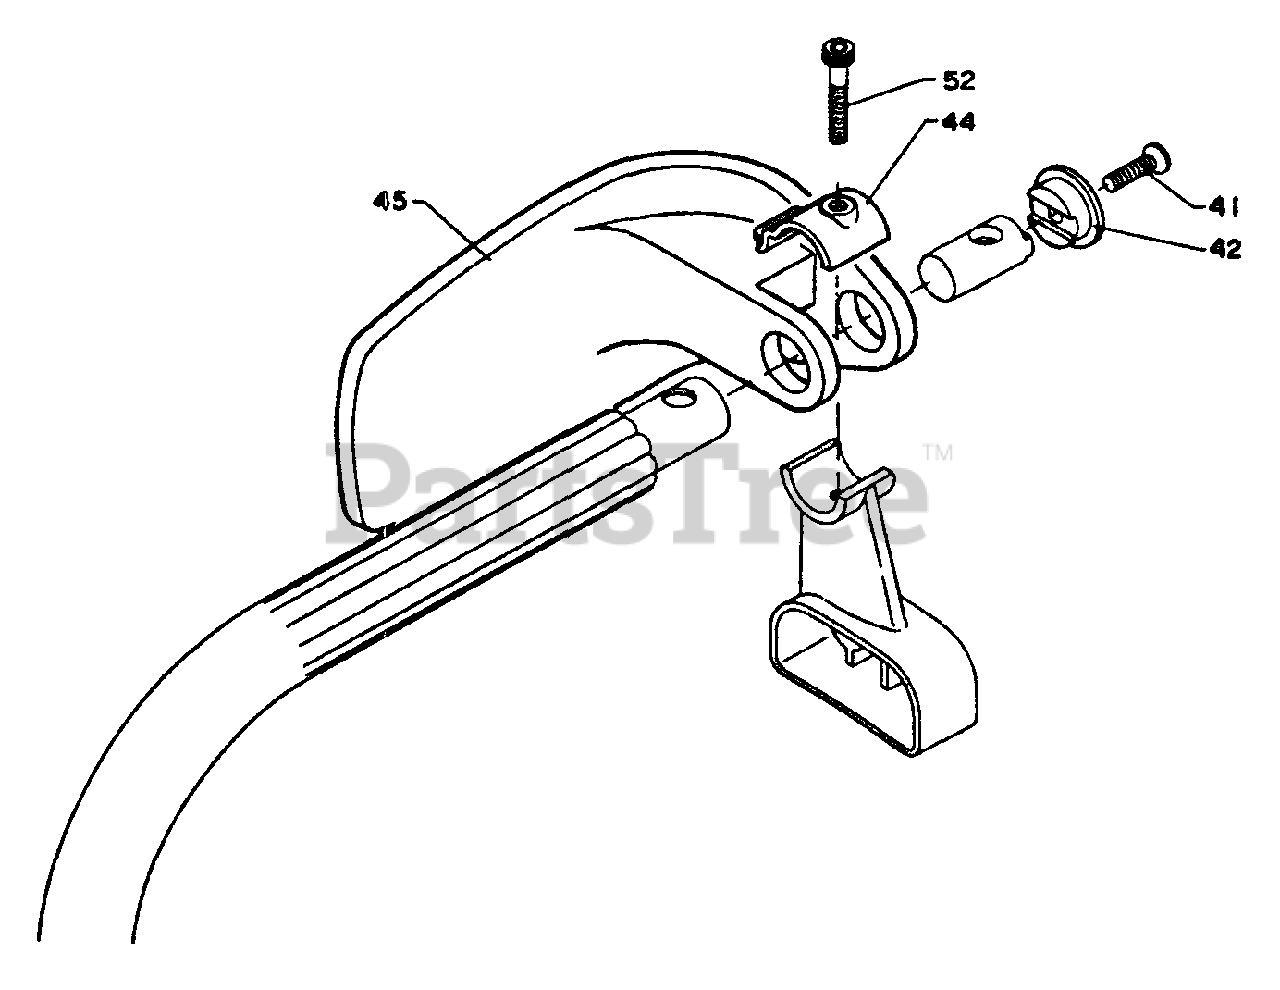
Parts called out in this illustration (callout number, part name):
41	SCREW - 5X20
42	RETAINER, GUARD
45	GUARD
52	SCREW - 5X35
